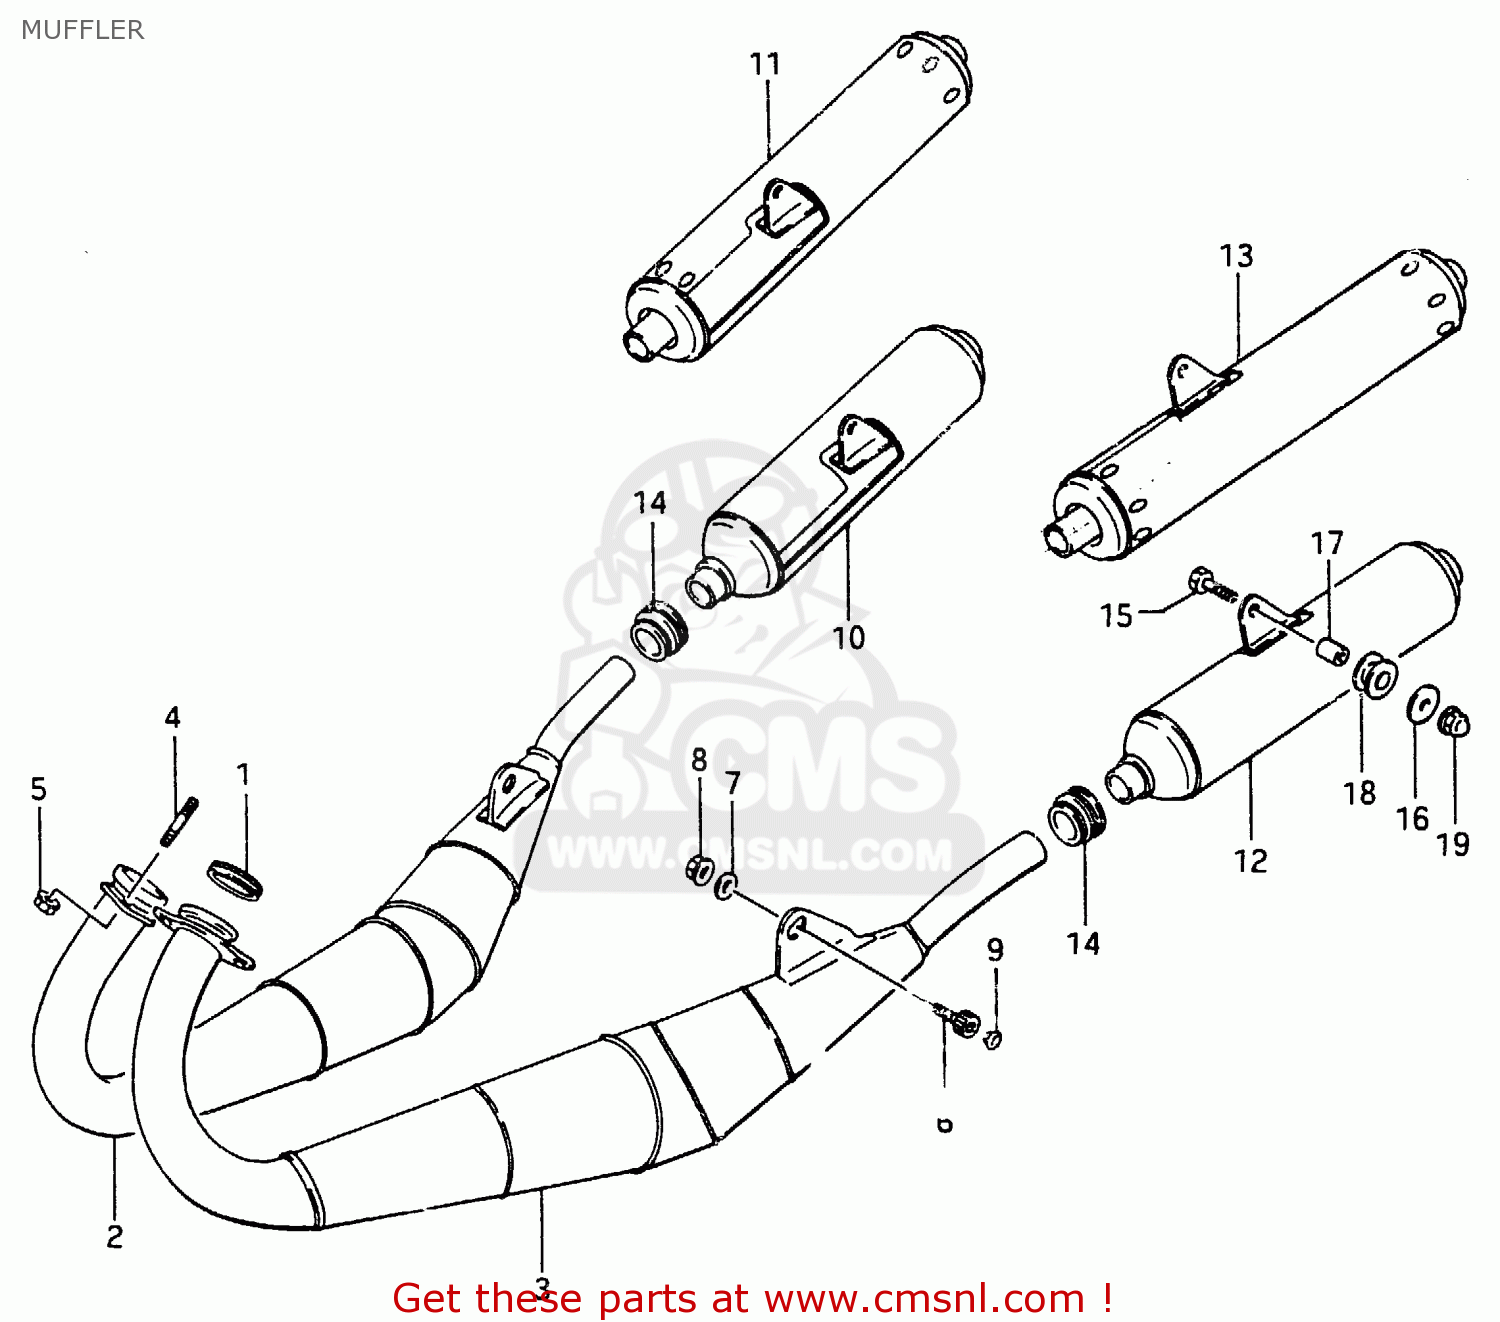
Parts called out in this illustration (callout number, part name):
1	GASKET, EXHAUST PIPE (NAS)
2	MUFFLER, 1ST RH
3	MUFFLER, 1ST LH
4	STUD BOLT
5	NUT
6	BOLT(10X33)
7	WASHER 10MM
8	NUT
9	CAP
10	MUFFLER, 2ND RH
11	MUFFLER, 2ND RH
12	MUFFLER, 2ND LH
13	MUFFLER, 2ND LH
14	CONNECTOR,MUFFLER
15	BOLT
16	WASHER
17	SPACER (8.6X12X17.5)
18	CUSHION
19	NUT,M8X1.25X12
